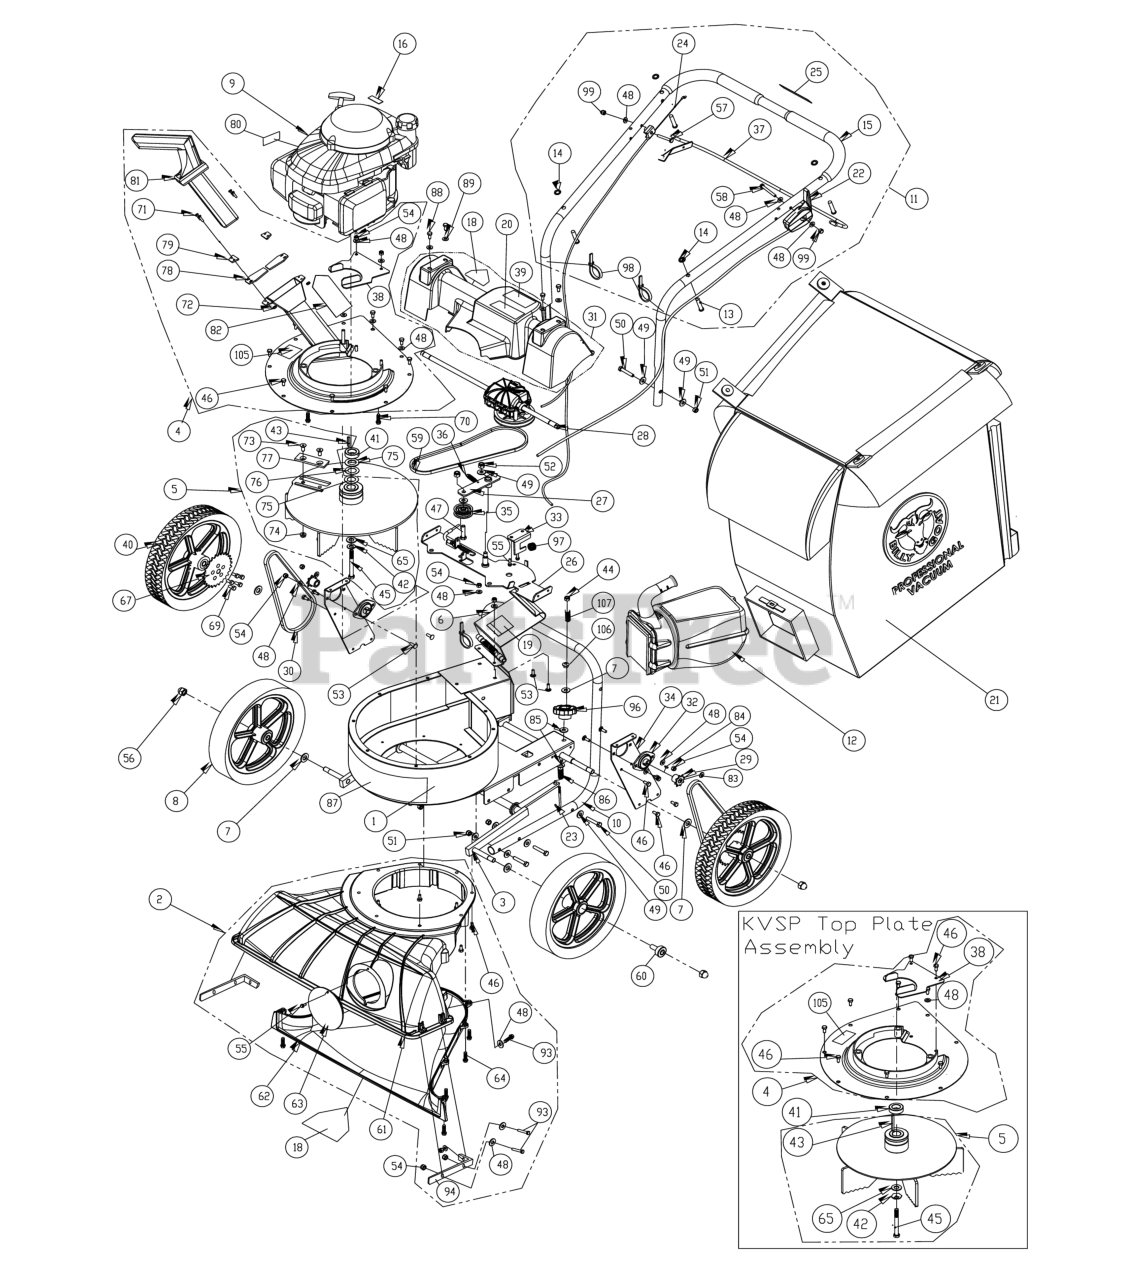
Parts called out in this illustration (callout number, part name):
1	HOUSING WA KV
2	NOZZLE MAINFRAME ASSY KV SERVICE
3	WA AXLE FRONT KV 2.0
4	PLATE TOP WA KVSP SERVICE
5	IMPELLER 14.25 WA SP VAC SERVICE
6	SEE: 890148
7	WASHER 1/2" SAE Z/P
8	SEE: 900509-S
9	ENGINE B&S PRO SERIES 875
10	HANDLE LOWER KV VAC
11	HANDLE UPPER KV SERVICE
12	QUICK DISCONNECT II
13	PIN CLEVIS 3/8 X 2.125
14	RETAINER 3/8" BOLT PUSH NUT
15	GRIP HANDLE 1"
16	LABEL HOT ENGINE
18	LABEL WARNING OPEI
19	LABEL DANGER FLYING DEBRIS
20	LABEL SAFETY PROTECT READ MANUAL
21	STANDARD BAG KV/TKV (SEE ACCESSORY PRICELIST)
22	CABLE THROTTLE 42"
23	BOLT J 3/8"-16 X 6" ZP
24	CABLE CLUTCH 40"
25	LABEL CLUTCH
26	BRACKET TRANS MOUNT WA
27	ARM IDLER WA KV
28	SEE: 891020-S
29	SPROCKET 8 TOOTH 41B8
30	CHAIN #43 X 58 PITCHES
31	GUARD DRIVE
32	SEE: 891025-S
33	BRACKET TRANS FIX KV
34	BRACKET CHAIN REINFORCE
35	PULLEY IDLER 2"OD X 3/8" ID
36	SPRING EXTENSION
37	BAIL CLUTCH KV
38	BRACKET IDLER BELT FINGER KV
39	LABEL DANGER
40	SEE: 890242-S
42	WASHER LOCK 3/8" S/T MED
43	KEY 3/16" SQ X 2 1/8"
44	NUT LOCK 3/8-16 LT WT THIN ZP
45	SCREWCAP 3/8"-24 X 3 1/2" GR.8 W/ PATCH
46	SCREW SELF TAP 1/4"-20 X 5/8" HWH TYPE F
47	BOLT IDLER 3/8"-16X1 3/4"
48	WASHER 1/4"SAE9/32"X5/8"X1/16"
49	WASHER 5/16" FLATWASHER Z/P
50	SCREWCAP 5/16"-18X1 3/4" HCS ZP
51	NUT LOCK 5/16"-18 HEX Z/P
52	NUT LOCK 3/8"-16 HEX
53	SCREWCAP 1/4"-20X3/4" HCS ZP
54	NUT LOCK 1/4"-20 HEX Z/P
55	SCREW PLASTITE X 3/4 HWH ZP
56	NUT 1/2"-13 CAP NP W/PATCH
57	SCREWCAP 1/4"-20X1 3/4" HCS ZP
58	SCREWCAP 1/4"-20X2" HCS ZP
59	BELT 3L310
60	BEARING BALL FLANGED
61	NOZZLE TOP HALF KV
62	NOZZLE BOTTOM HALF KV
63	PLUG HOUSING PLAIN GREEN
64	SCREW PLASTITE 1/4-10 X 1 HWH ZP
65	WASHER 1.5 OD X .453 ID X .25 THK
67	SPROCKET 65A26 26 TOOTH
69	SCREW SELFTAP 1/4"-14X3/4" TYP B
70	SCREWCAP 3/8"-16X2 1/2" TAPTITE
83	RING RETAINING 1/2"
84	KEY WOODRUFF 1/8" X 1/2"
85	WASHER 1/2"FC9/16"X1 3/8"X7/64"
86	SPRING COMPRESSION 1/2 X 4.31
87	LABEL BADGING KV
88	SCREW SM 1/4" X 3/4" DRILL PT. BLACK
89	WASHER 1/4"SAE BLACK OXIDE
92	BOLT CARRIAGE 1/4" X 3/4"
93	SCREWCAP 1/4"-20 X 1" HCS ZP
94	BRACKET NOZZLE ASSY KV
96	KNOB 3/8-18 RED PRINTED
97	SPRING LEVER GZ
99	NUT ACORN 1/4-20 HIGH CROWN
106	GROMMET FLANGE 1/2" MOLDED
107	SPRING COMPRESSION
